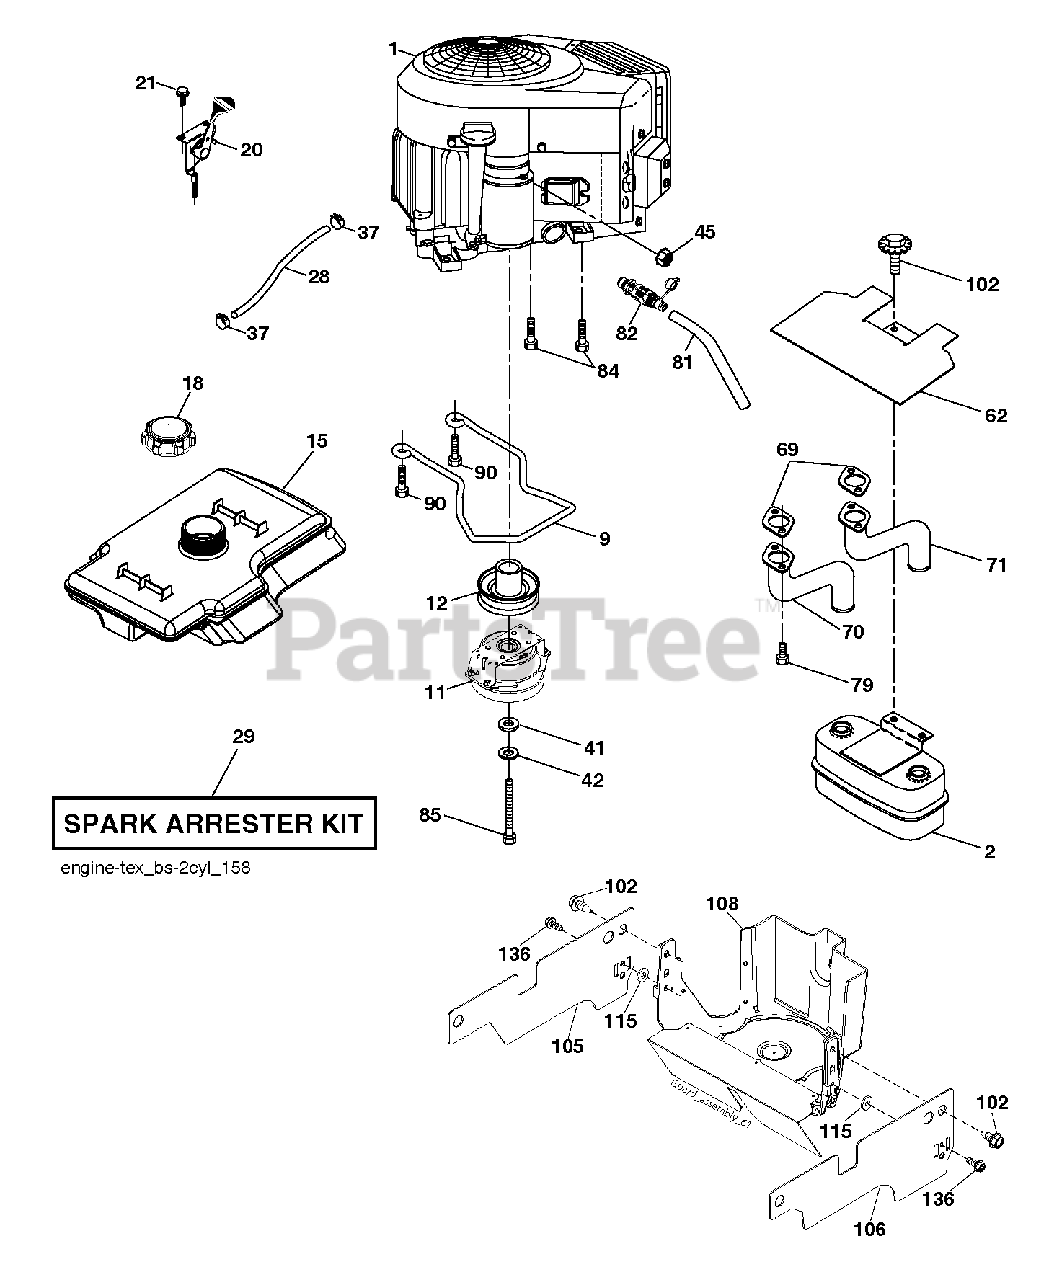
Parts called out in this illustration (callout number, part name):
2	MUFFLER.ASM.TWN.EXTNDED.DFLCTR
9	KEEPER.BELT.ENG.4.25"2.BLT.431
11	CLUTCH.OGURA.4.4PD.GT1.5-EH13V
12	PULLEY.ENGINE.TUFFTORQ
15	FUEL TANK
18	CAP.ASSY.FUEL.3".N-EPA.BLK.428
20	THROTTLE.COBRA.38"READSTART.BK
21	SCREW.#10 X 0.750.BOS
28	REPL BY 532 00 85-43
29	KIT.SPARK ARRESTOR 794945 B&S
37	HOSE CLAMP
42	LOCKWASHER
45	NUT
62	SHIELD.HEAT.MUFFLER
69	GASKET.MUFFLER
70	EXHAUST.TUBE.LH.BS/TWIN
71	EXHAUST.TUBE.RH.B&S.TWIN.INTEK
79	SCREW.SOCKET.HEAD.5/16-18
81	TUBE, DRAIN OIL ASM.
82	VALUE.OIL.DRAIN
84	SCREW.3/8-16
85	CLUTCH BOLT7/16-20X3.5 GR524HR
90	SCREW 3/8-16X1
102	SCREW
105	SHIELD.SIDE.LH.3842"TEX FRN.BK
106	SHIELD.SIDE.LH.3842"TEX FRN.BK
108	ENGINE COVER
115	PALNUT 1/4
136	SCREW.1/4-20X5/8
